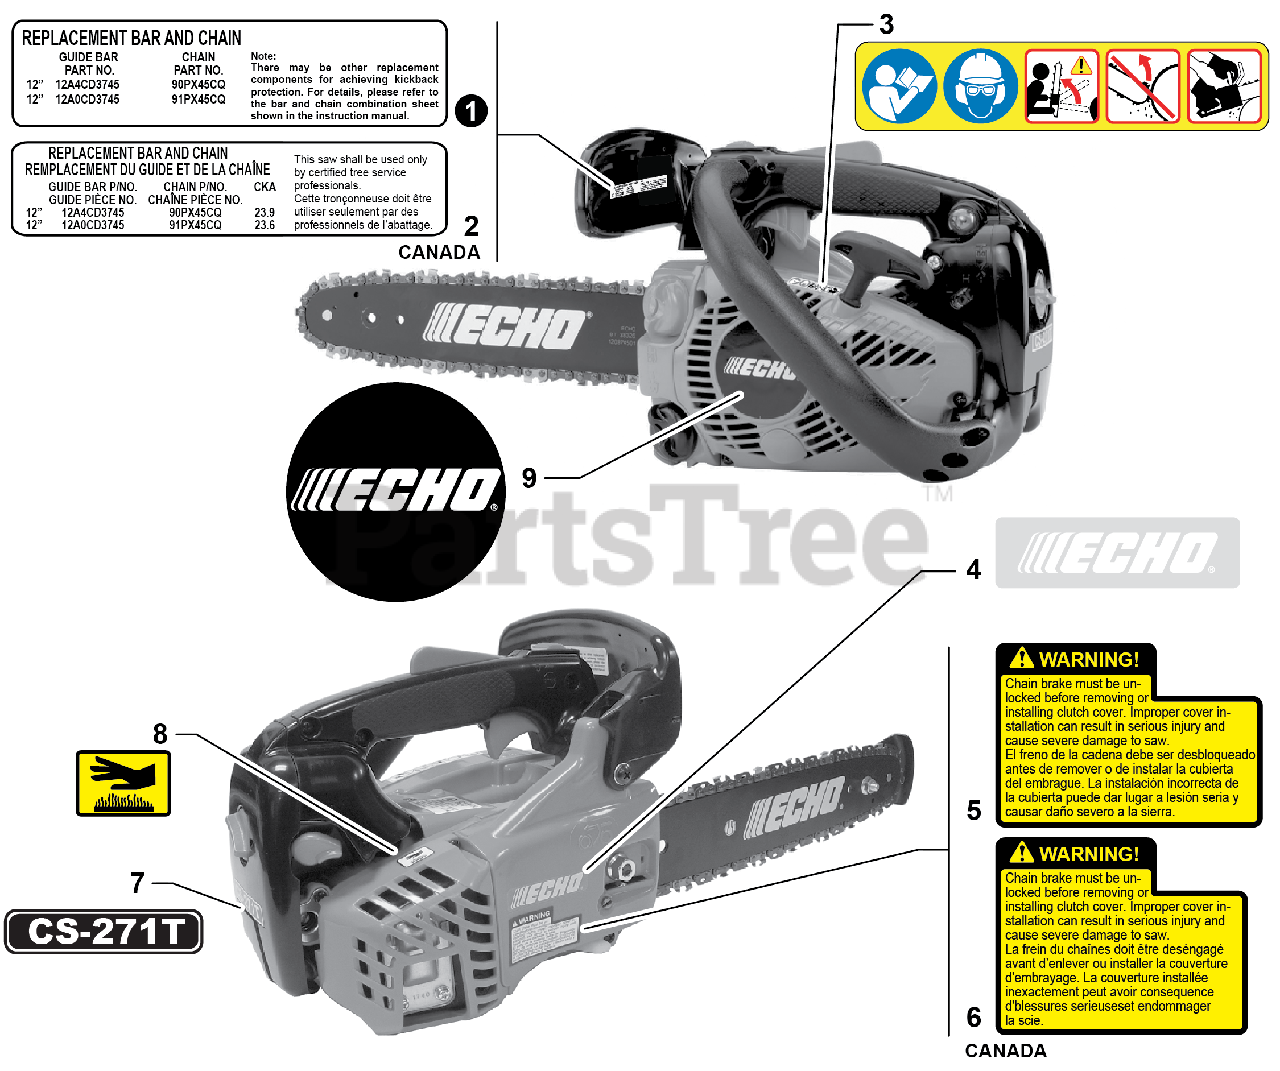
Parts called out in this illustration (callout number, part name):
1	LABEL - BAR & CHAIN
2	LABEL - BAR & CHAIN
3	LABEL - CAUTION
4	LABEL - ECHO
5	LABEL - WARNING
6	LABEL - WARNING
7	LABEL - MODEL CS-271T
8	LABEL - CAUTION - HOT
9	LABEL - ECHO
